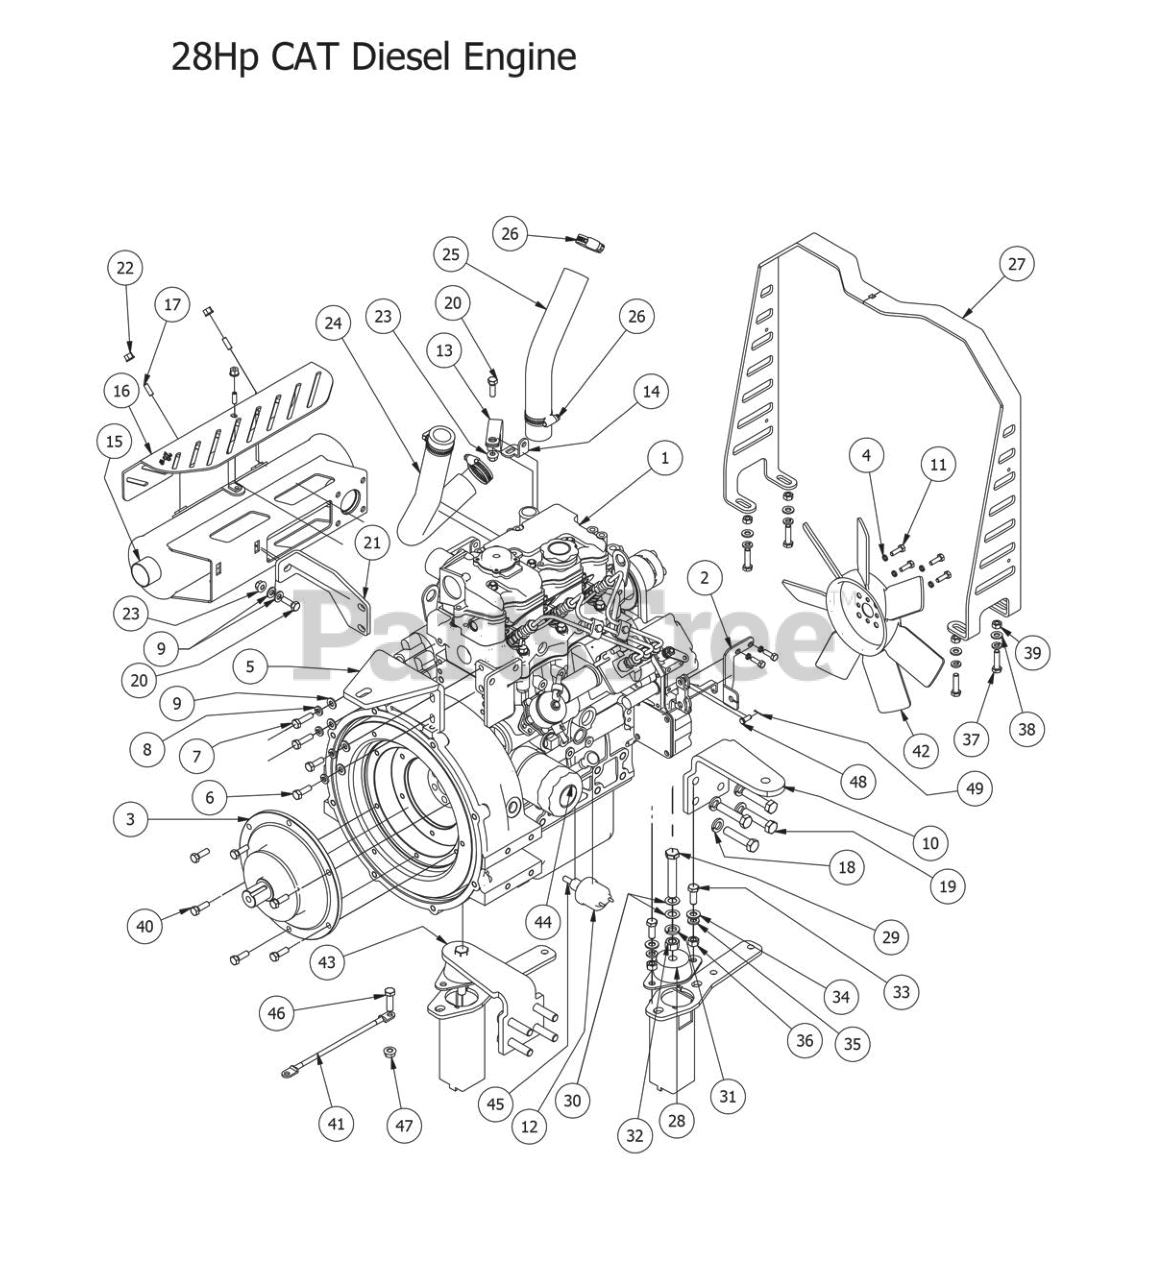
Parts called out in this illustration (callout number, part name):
1	28hp CAT Diesel Engine
2	Diesel Throttle Bracket (4 Tier)
3	Stub Shaft
4	1/4" Lock Washer
5	Air Cleaner Support Diesel
6	M8 x 1.25 x 25mm Hex Head Bolt
7	M8 x 1.25 x 30mm Hex Head Bolt
8	5/16" Lock Washer
9	5/16" Flat Washer
10	Diesel Motor Side Support Right
11	6mm x 20mm Bolt
12	Pressure sender-2012 Gauge and up
13	Diesel Clamp 1 3/4" Vinyl
14	Diesel Radiator Hose Clamp Bracket
15	28/35hp Caterpillar Muffler
16	Diesel Muffler Guard (28hp)
17	1/4" x 3/4" Set Screw
18	1/2" Lock Washer
19	12mm Bolt- Diesel
20	5/16" x 1" Bolt
21	Muffler Brace Diesel
22	1/4-20 Nylon Insert flange Nut
23	5/16" Flange Nut
24	Bottom Radiator Hose for Diesel
25	Top Radiator Hose for Diesel
26	1 1/8" Hose Clamp
27	Hood Holder Diesel
28	Rubber Isolator
29	1/2" x 3" Hex Bolt
30	1/2" Brass Washer
31	1/2" Lock Washer
32	1/2" Hex Nut
33	3/8" x 1" Hex Bolt
34	3/8" Flat Washer
35	3/8" Lock Washer
36	3/8" Hex Nut
37	5/16" x 1 1/4" Hex Bolt
38	5/16" Flat Washer
40	5/16-18 X 1 Button Head Bolt
41	Starer To Chassis Cable - Diesel
42	Engine Fan - Diesel
43	Diesel Side Motor Mount Left
44	CAT Oil Filter
45	Brass Washer For Weld On Hinge
46	3/8" x 1 1/2" Hex Bolt
47	3/8" Flange Nut
48	1/4-5/8 Clevis Pin
49	3/32 X 1/2 Cotter-pin
